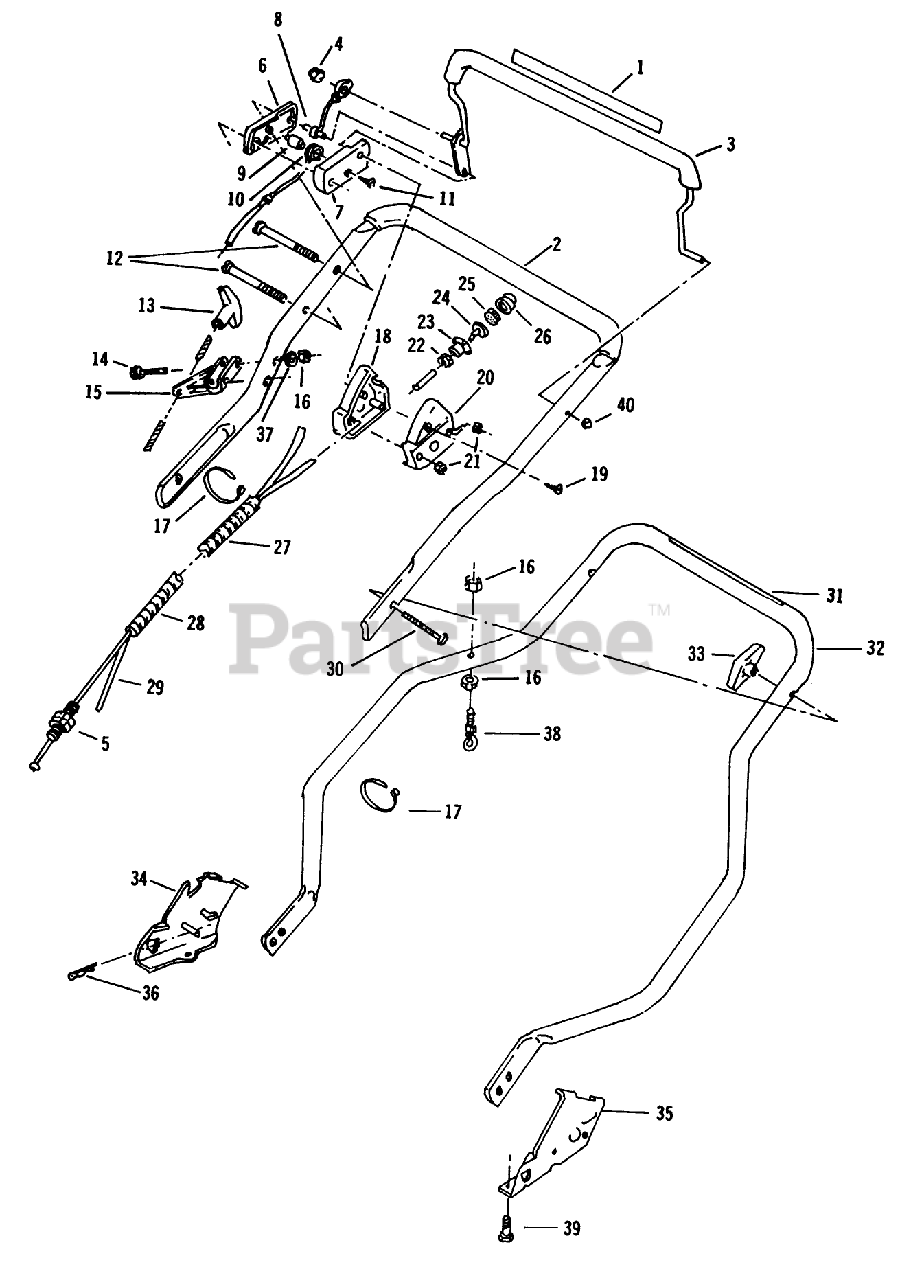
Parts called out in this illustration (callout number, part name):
2	Top Handle and Grip Assembly
4	NUT ACORN
5	CONTROL CABLE WES
8	COLUMN
9	PIN SKF
11	SCREW
13	HANDLE,STARTER
16	LOCKNUT E
19	SCREW LAWRENCE
21	NUT C/LOCK E
22	LOCKNUT S
25	FILTER S
30	BOLT QUALITY
33	NUT-WING
36	HAIR PIN
37	WASHER
38	EYE BOLT WAS MFG
39	SCREW
